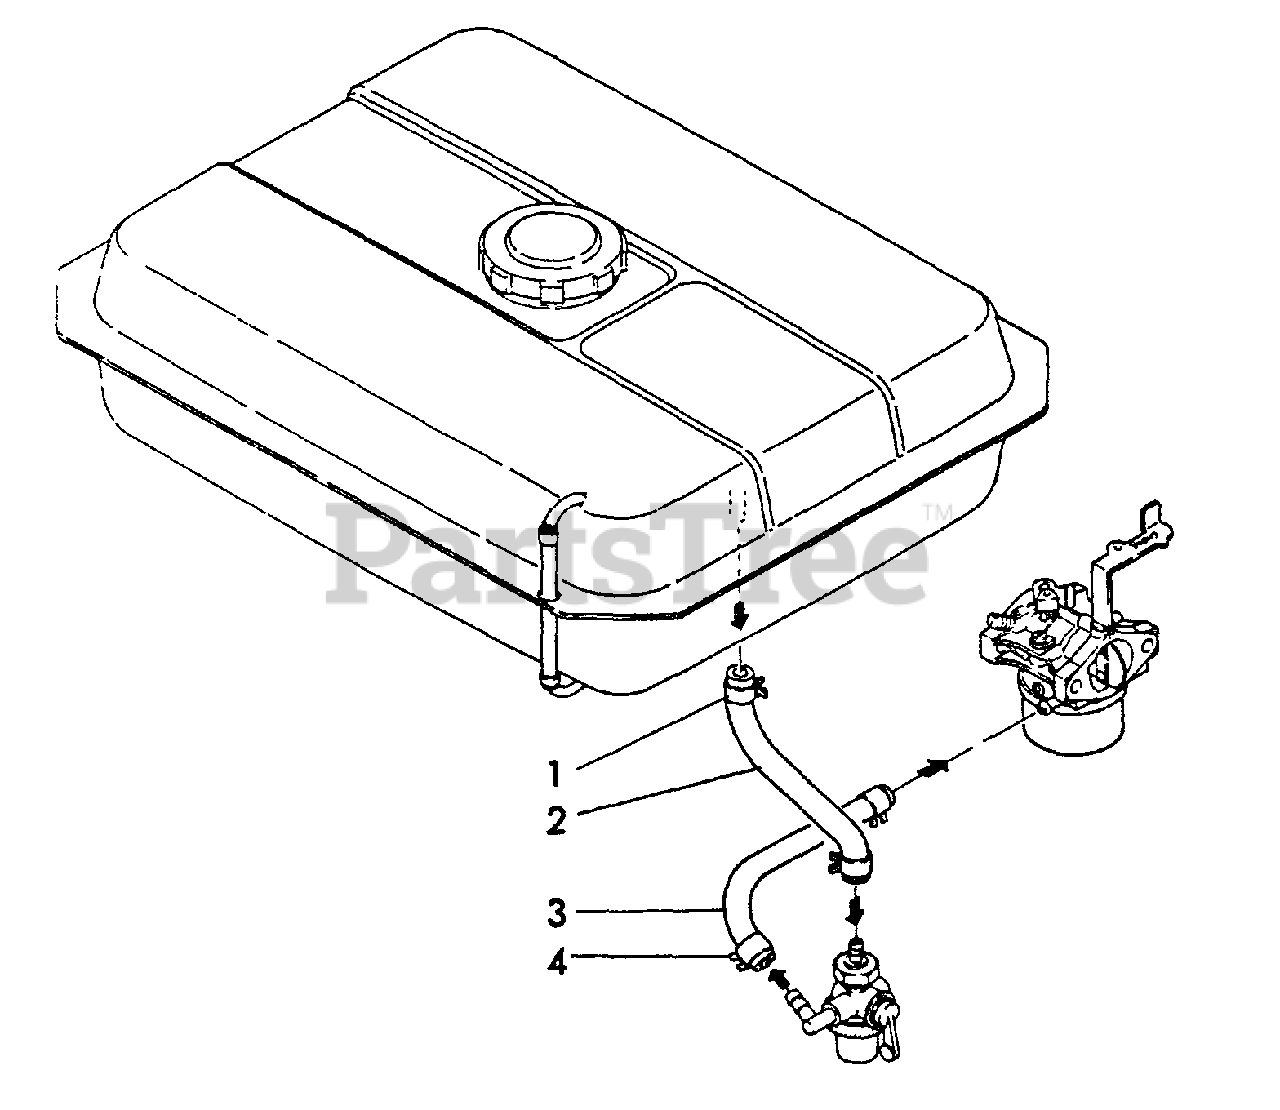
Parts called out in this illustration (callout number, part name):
1	CLAMP, HOSE
2	PIPE - FUEL
3	PIPE - FUEL
4	CLAMP, HOSE - 10
